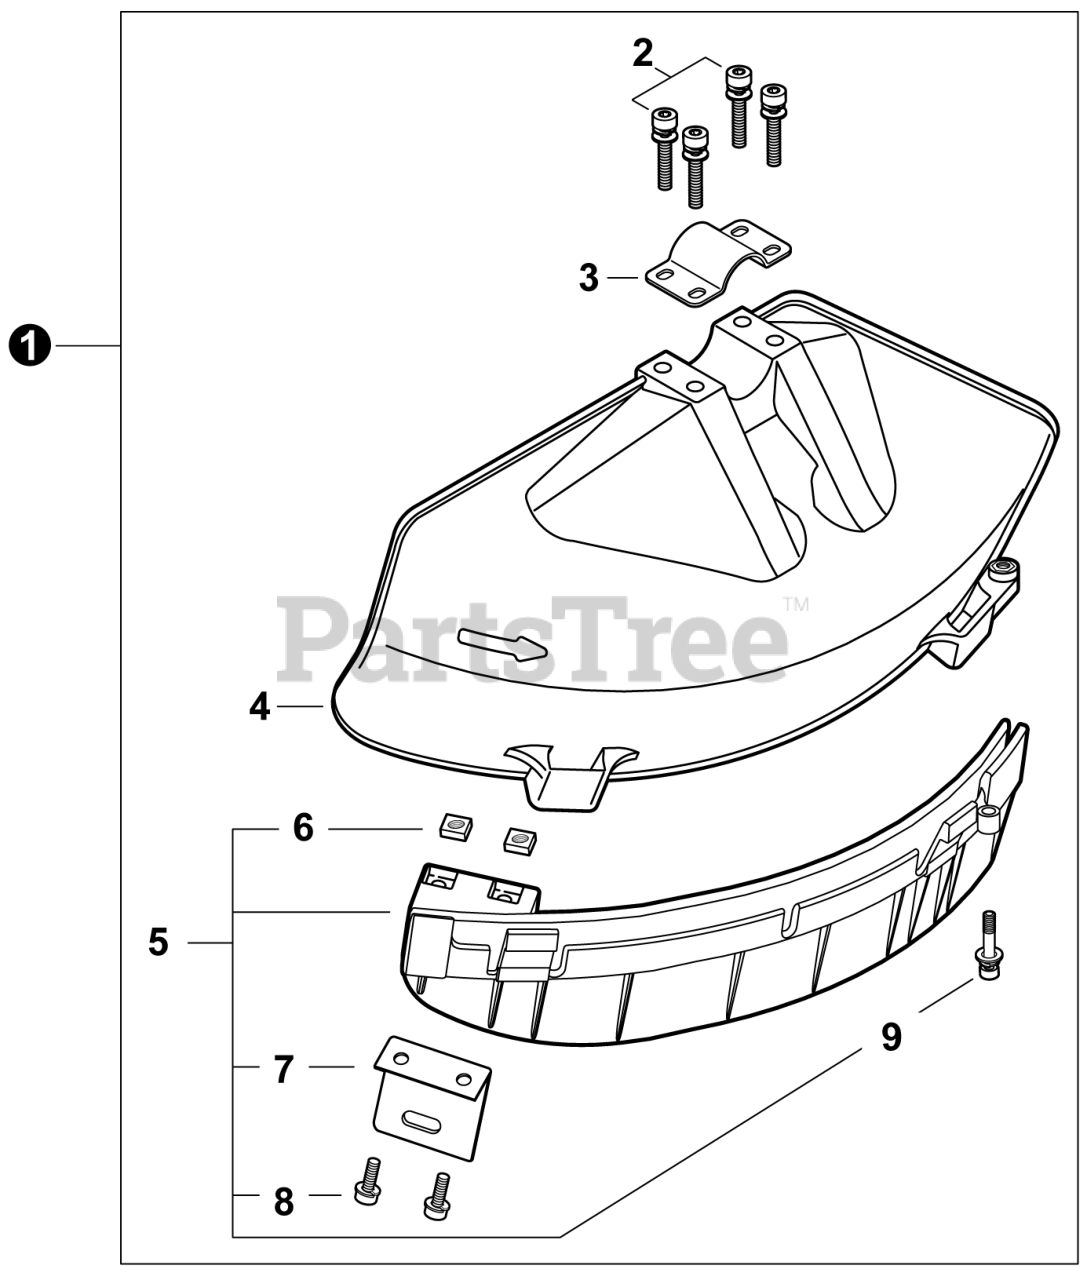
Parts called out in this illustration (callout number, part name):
1	DEBRIS SHIELD KIT
2	BOLT M5x45
3	CLAMP, UPPER
4	SHIELD, DEBRIS - BLADE
5	DEBRIS SHIELD EXTENSION ASSY
8	BOLT 5x16
9	BOLT M5x22
